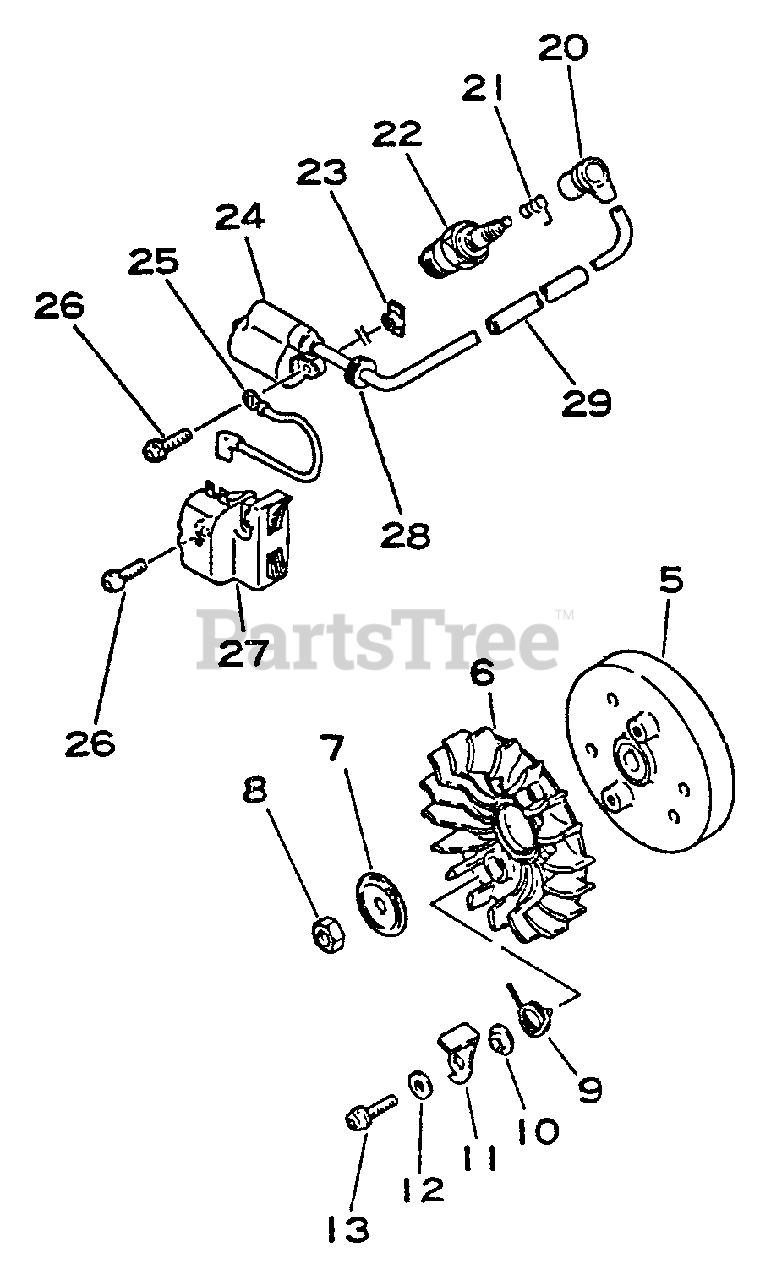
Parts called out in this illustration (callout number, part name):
5	FLYWHEEL
6	FAN
7	WASHER 8.2×31×0.8
9	SPRING, RETURN
10	SPACER, PAWL
11	PAWL, STARTER
12	WASHER, FLAT 5.5×10×0.8
13	SCREW - 5×14
20	CAP, SPARK PLUG
21	TERMINAL, SPARK PLUG
22	SPARK PLUG - CJ-6Y
24	COIL, IGNITION
26	SCREW - 4×20
27	COIL, IGNITION
29	TUBE
